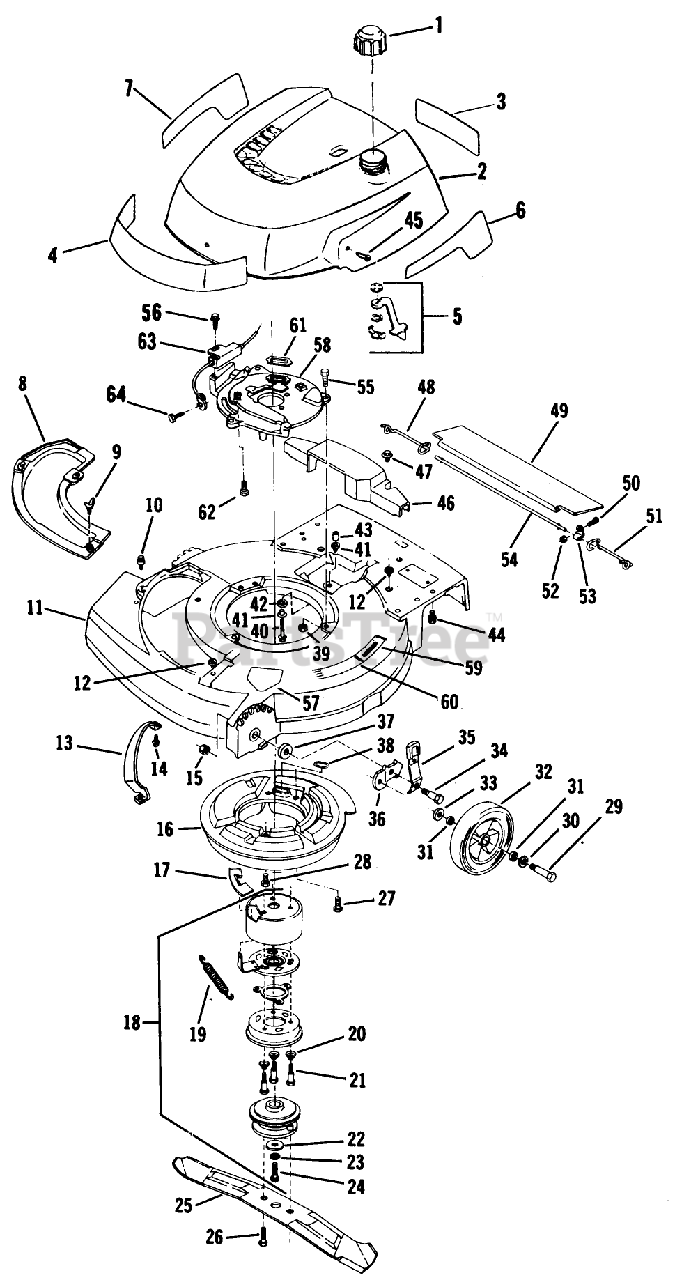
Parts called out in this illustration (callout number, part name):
9	WING SCREW LAWRE
13	BAR-TOE
15	LOCKNUT
18	Clutch Brake Assembly
19	SPRING
21	SCREW,SHOULDER SM
22	WASHER
25	Blade-21"
26	SCREW SEMS
28	SCREW
29	BOLT WHEEL
30	SPACER
31	WASHER
32	WHEEL & TIRE KIT
33	WASHER WROUGHT
37	WASHER
38	SEAL
39	NUT-LOCK F
41	SPACER ECK PRES
42	Grommet
43	SPACER
44	SCREW
45	SCREW S
48	SPRING;TRAILING SHIELD RH
49	SHIELD
51	SPRIG T/SHLD ASOC
52	LOCKNUT E
53	CLAMP ROD KMC
54	ROD 21" ADVANCE
55	SCREW
56	SCREW
60	PAD FOOT
61	PAD FOOT
62	Screw-Eng. Mtg. Plt. to Blk.
63	CONTROL CABLE
